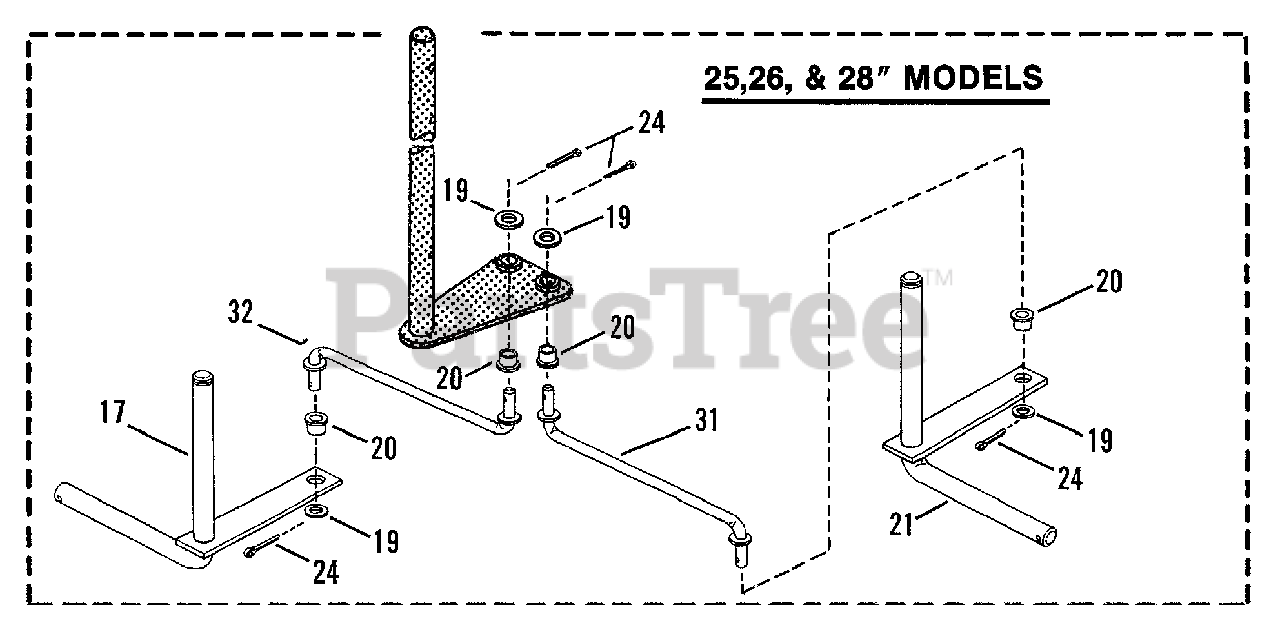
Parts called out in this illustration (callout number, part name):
17	King Pin, R.H.
19	WASHER, 3/8" Flat
20	BUSHING
21	King Pin, L.H.
24	COTTER-PIN, 1/8 x 3/4"
31	TIE-ROD, Left Side (25, 26 & 28" Models)
32	TIE-ROD, Right Side (25, 26 & 28" Models)
